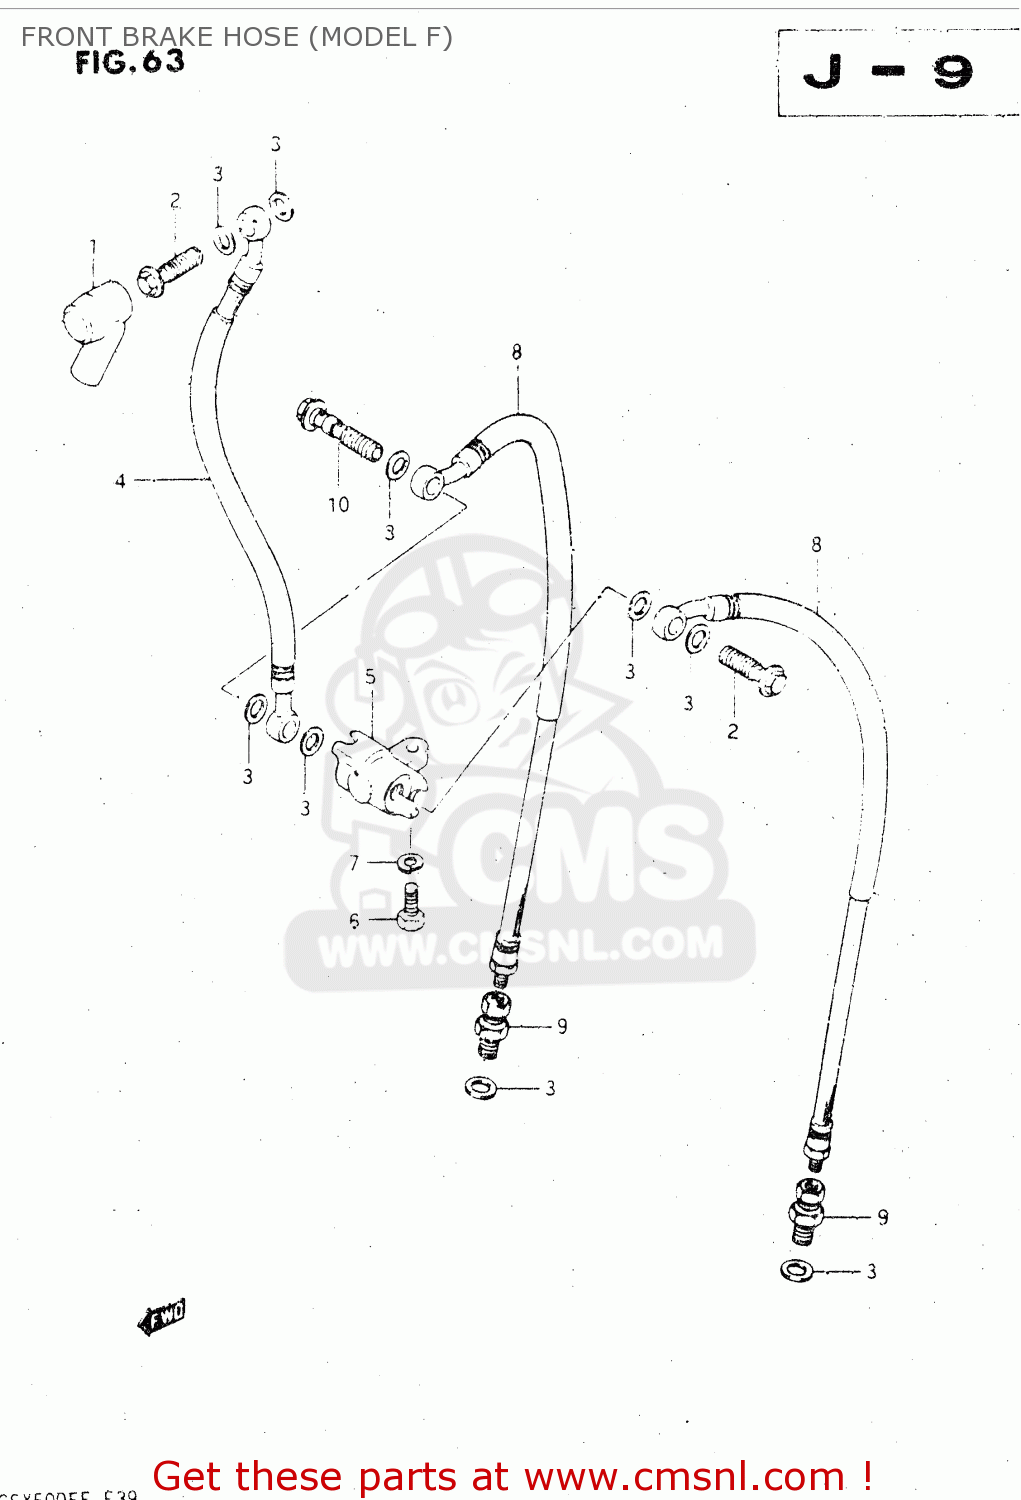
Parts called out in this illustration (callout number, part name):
1	BOOT,MASTER CYLINDER
2	BOLT UNION
3	WASHER(10X15X1.5)
4	HOSE,FRONT BRAKE
5	JOINT,BRAKE HOSE
6	BOLT
7	WASHER,LOCK
8	HOSE,BRAKE NO.2
9	ADAPTER,BRAKE HOSE
10	BOLT UNION
